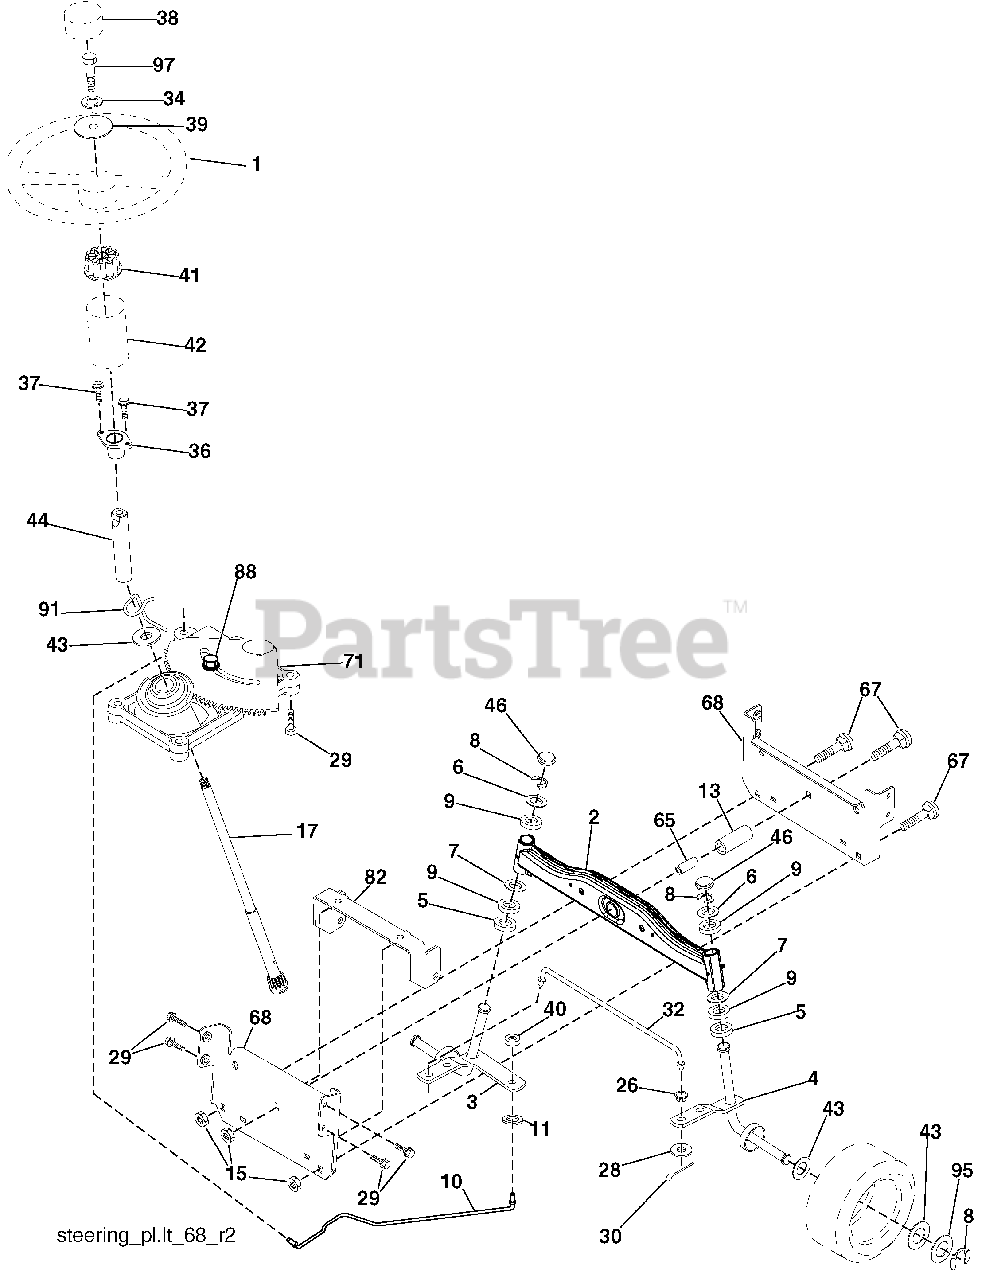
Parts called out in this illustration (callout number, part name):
1	Wheel Steering
2	Axle Asm
3	Spindle Asm LH
4	Spindle Asm RH
5	Bearing Race Thrust Harden
6	Washer 25/32 x 1-5/8 x 16 Ga.
7	Washer 27/32 x 1-1/4 x 16 Ga.
8	Ring Klip #t5304-75
9	Bearing Col Strg Blk
10	Link Drag
11	Washer Lock Hvy Hlcl Spr 3/8
13	Spacer earing Axle Front
15	Hexflange Lock
17	Shaft Asm Strg
26	Bushing Link Drag Blk LR
28	Washer 13/32 x 7/8 x 16 Ga.
29	Screw 3/8-16 x 3/4
30	Pin Cotter 1/8 x 3/4 Cad
32	Rod Tie Wire Form 19 75 Mech
34	Washer Lock Hvy Hlcl Spr 5/16
36	Bushing Strg 5/8 Id Dash
37	Screw
38	Cap Wheel Steer Ayp
39	Washer 11/32 ID x 2-3/8 OD x 12 Ga.
40	Nut Crownlock 3/8-24
41	Adaptor Wheel Strg
42	Boot Dash Mtl Steering Blk
43	Washer 25/32 x 1 1/4 x 16 Ga.
44	Extension Steering
46	Cap Spindle Fr Top Blk
65	Spacer Brace Axle
67	Bolt RDHD SQNK 3/8-16 x 2-1/4
68	Brace Axle
71	Steering Asm.
82	Bracket Susp Chassis Front
88	Bolt Shoulder 7/16-20
91	Clip Steering
95	Washer Harden .793 x 1.637 x 060
97	Bolt 5/16-18 unc x 4"L Hlcl Spr. 5/16
